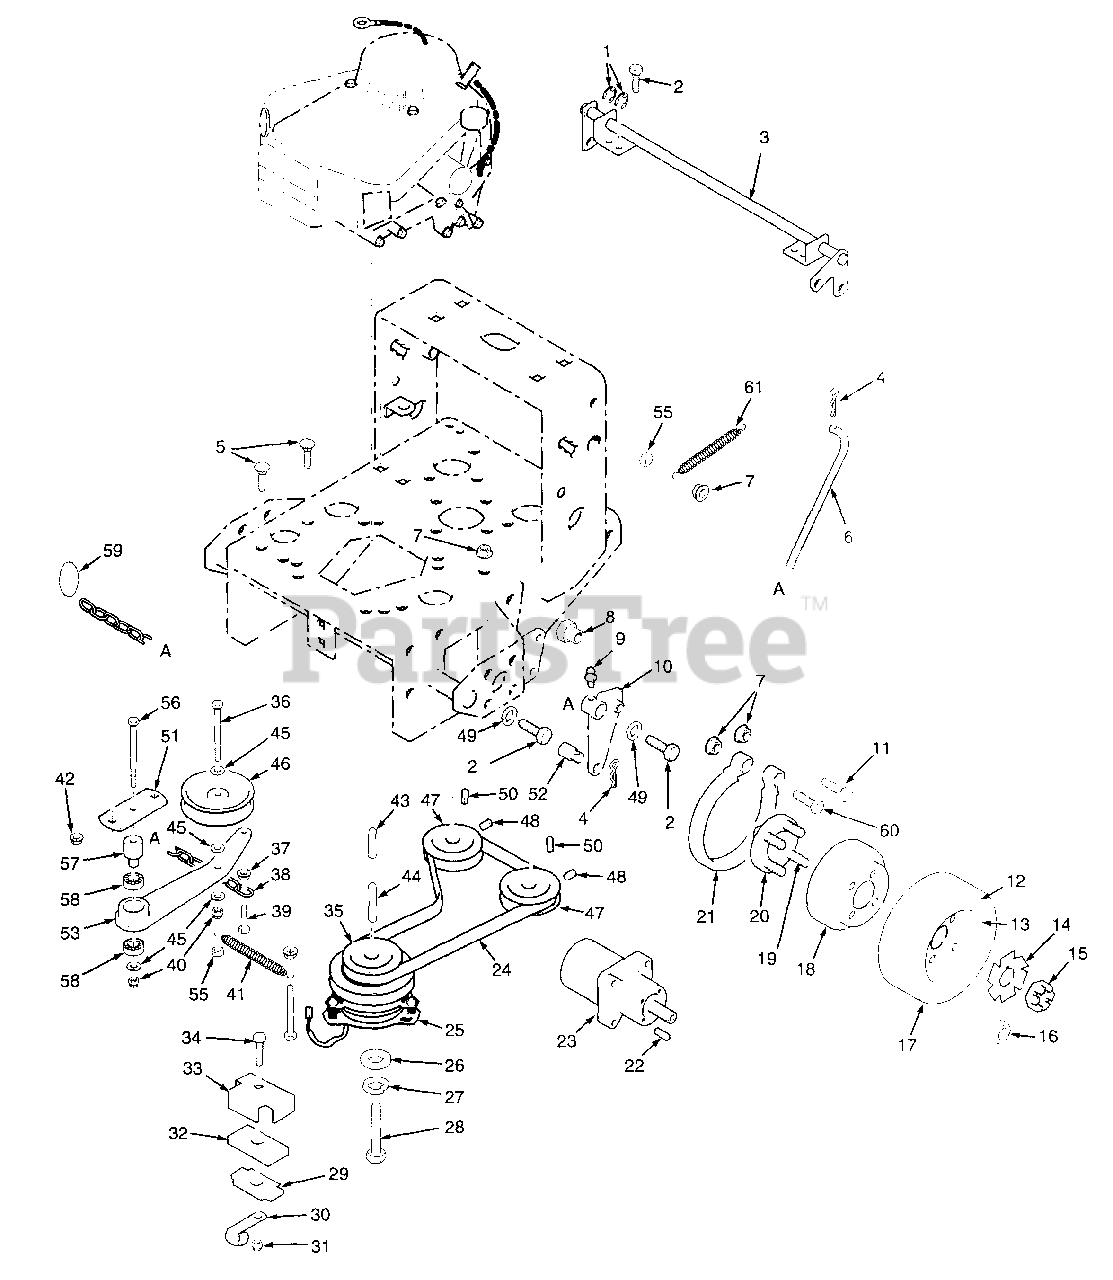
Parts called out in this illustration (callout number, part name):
1	Retaining Ring, 3/4" Ext. "E"
2	Bolt, Hex Head 3/8-16 x 1"
3	Brake Shaft Assembly Weldment
4	Hair Pin, Cotter (.094 x 1.62)
5	Bolt, Carriage 5/16-18 x .75"
6	Brake Rod, Lower
7	Nut, Hex Serrated Flange 3/8-16
8	Bushing, Brake
9	Grease Fitting
10	Brake Actuator Weldment, LH
11	Bolt, Hex Head 3/8-16 x 2.25"
12	Tire, 18 x 8.50-8, 4 Ply
13	Rim Assembly
14	Lockwasher, Wheel Motor
15	Nut, Hex Castle 3/4-28
16	Nut, Lug
17	Wheel Assembly (#12 tire mounted to #13 rim)
18	Brake Drum
19	1/2-20 Serrated Bolt
20	Hub, Wheel
21	Brake Band, 7.5"
22	Key, Woodruff 3/16 x .75"
23	Wheel Motor
24	Belt, Pump Drive
25	Electric Clutch
26	Flatwasher, 7/16" (.469 x 1.75 x .25)
27	Lockwasher, 7/16" Spring
28	Bolt, Hex Head 7/16-20 x 2.75"
29	Plate, Backing
30	Clamp, Wire Loom
31	Nut, Hex Elastic Stop 5/16-18
32	Rubber Pad, Clutch Stop
33	Retainer, Clutch Stop
34	Bolt, Hex Head 5/6-18 x 1.75"
35	Pulley, Pump Drive-Engine
36	Bolt, Hex Head 3/16 x 2.75"
37	Nut, Hex Serrated Flange 1/4-20
38	Chain
39	Bolt, Hex Head 1/4-20 x 1.25"
40	Nut, Hex Elastic Stop 3/8-16
41	Spring, Pump Belt Idler
42	Nut, Hex Serrated Flange 5/16-18
43	Key, 1/4 x 1/4 x 1"
44	Key, 1/4 x 1/4 x 2.75"
45	Flatwasher, 3/8" (.391 x .938 x .105)
46	Pulley, Idler 4.5"
47	Pulley, Pump Shaft
48	Setscrew, 5/16-18 x 3/8"
49	Lockwasher, 3/8" Spring
50	Key, 5mm x 5mm x 25mm
51	Base, Idler Pivot
52	Swivel Joint
53	Idler Arm Weldment, Pump
54	Bolt, Hex Head 3/8-16 x 3.5"
55	Locknut, 3/8-16 Center Lock
56	Bolt, Hex Head 3/8-16 x 3"
57	Pivot, Idler (Long)
58	Ball Bearings
59	Ring, Split
60	Bolt, Hex Head 3/8-16 x 2.63
61	Spring, Return
